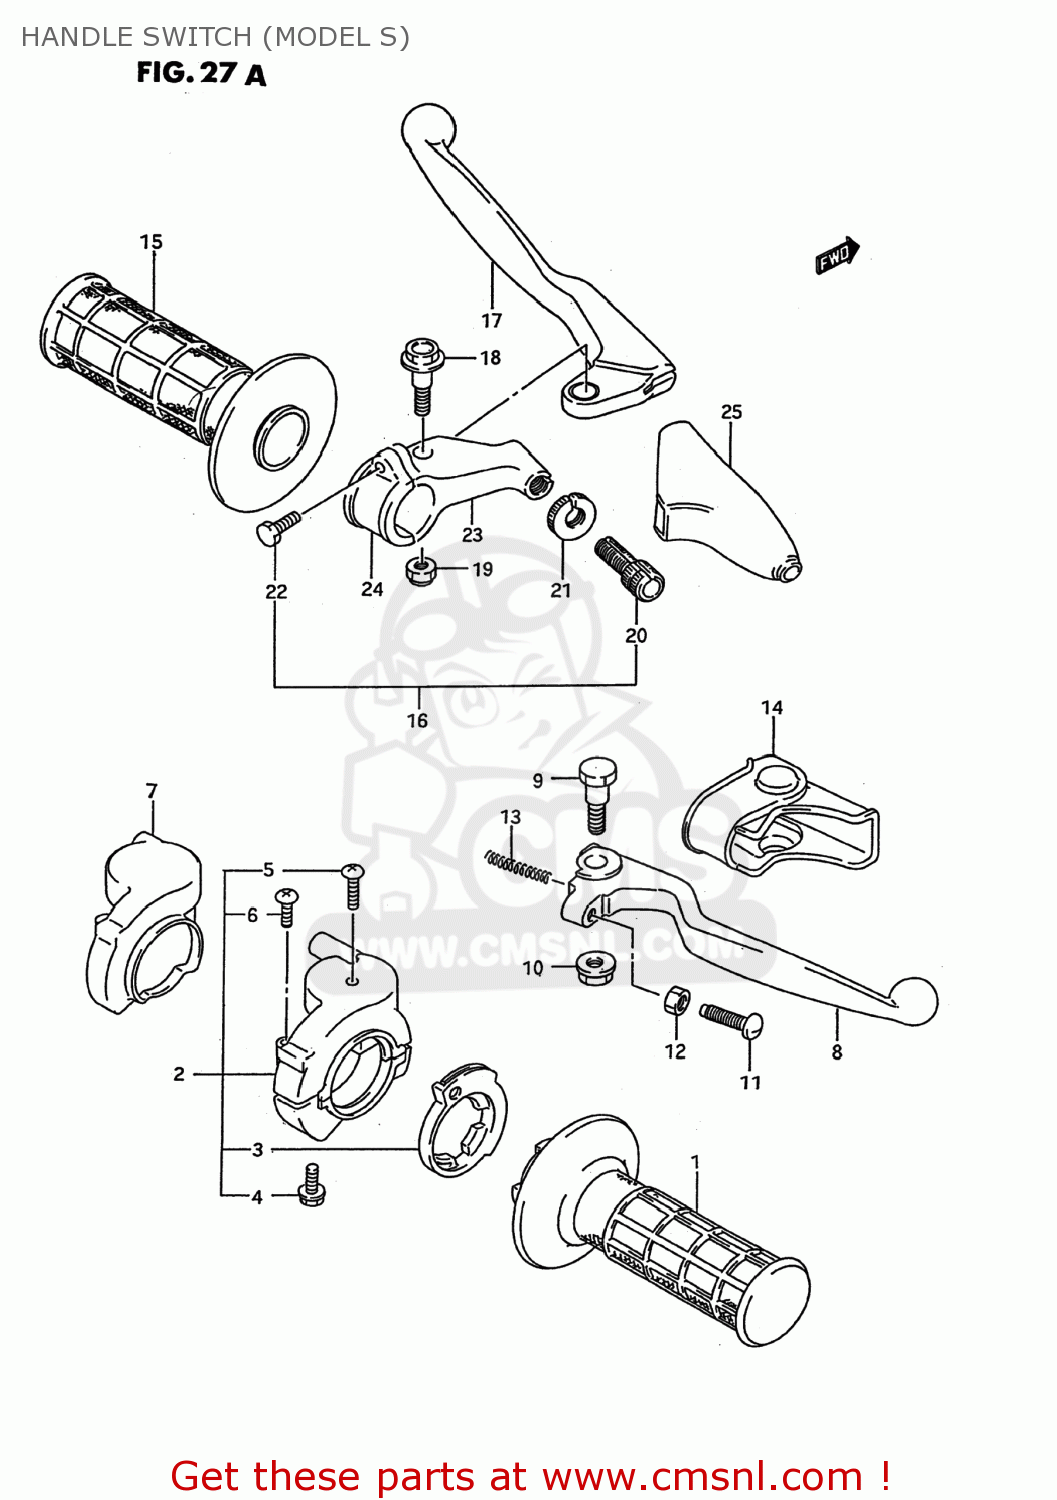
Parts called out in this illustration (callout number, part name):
1	GRIP,THROTTLE
2	CASE ASSEMBLY,THROTTLE
3	ROTOR,THROTTLE
4	BOLT 6X25
5	SCREW,UPPER
6	SCREW
7	COVER,THROTTLE CASE
8	LEVER,BRAKE
9	BOLT,BRAKE LEVER
10	NUT,BRAKE LEVER
11	BOLT,ADJUST
12	NUT ,5MM
13	SPRING,RETURN
14	COVER,BRAKE LEVER
15	GRIP,L
16	LEVER ASSEMBLY,CLUTCH
17	LEVER,CLUTCH
18	BOLT,LEVER
19	NUT 6MM
20	ADJUSTER,WIRE
21	NUT,LOCK
22	BOLT
23	HOLDER,CLUTCH LEVER
24	BRACKET,CLUTCH LEVER HOLDER
25	COVER,CLUTCH LEVER
